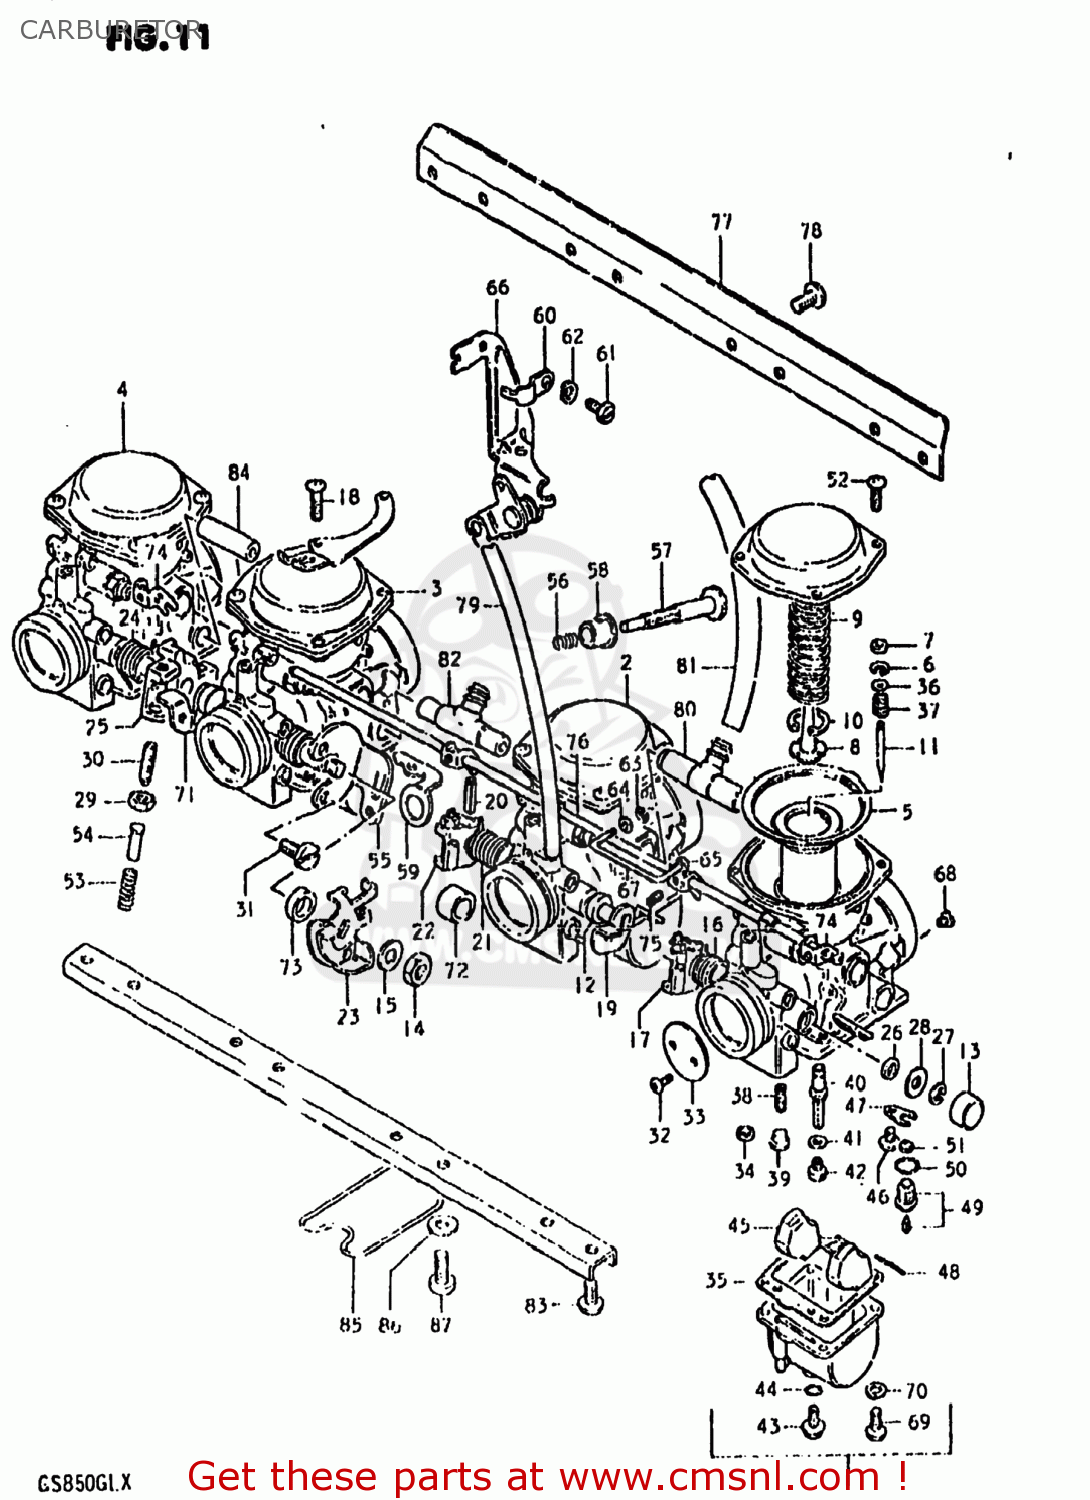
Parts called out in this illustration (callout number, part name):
1	CARBURETOR ASSEMBLY
2	CARBURETOR ASSEMBLY
3	CARBURETOR ASSEMBLY
4	CARBURETOR ASSEMBLY
5	DIAPHRAGM
6	CLIP,NEEDLE
7	RING
8	HOLDER,GUIDE
9	SPRING
10	E RING
11	NEEDLE JET
12	GASKET,THROTTLE SHAFT (NAS)
13	CAP
14	NUT
15	WASHER
16	SPRING,THROTTLE SHAFT
17	SHAFT,THROTTLE
18	SCREW
19	SHAFT ASSEMBLY
20	PIN,THROTTLE SHAFT
21	SPRING,THROTTLE SHAFT
22	LEVER,THROTTLE SHAFT
23	LEVER ASSEMBLY,THROTTLE
24	SPRING,THROTTLE SHAFT
25	SHAFT,THROTTLE
26	SEAL
27	E RING
28	GASKET,THROTTLE SHAFT (NAS)
29	NUT
30	SCREW
31	SCREW
32	SCREW
33	VALVE,THROTTLE
34	GASKET (NAS)
35	GASKET,FLOAT CHAMBER (NAS)
36	WASHER
37	SPRING
38	JET,PILOT
39	PLUG,NEEDLE JET
40	JET,NEEDLE
41	WASHER,NEEDLE NOZZLE
42	JET,MAIN(115)
43	PLUG,DRAIN
44	GASKET (NAS)
45	FLOAT
46	SCREW
47	PLATE
48	PIN,FLOAT
49	VALVE ASSEMBLY,NEEDLE
50	O RING
51	FILTER
52	SCREW
53	SPRING,THROTTLE SCREW
54	PIN,THROTTLE LEVER
55	BRACKET,THROTTLE ADJUST
56	SPRING
57	SCREW
58	BUSH
59	BRACKET,THROTTLE ADJUST
60	BRACKET,STARTER
61	BOLT
62	LOCK WASHER
63	CAP,LEVER
64	SEAT,SPRING
65	LEVER ASSY
66	BRACKET
67	ROD,STARTER LEVER
68	JET,AIR(190)
69	SCREW
70	LOCK WASHER
71	SHAFT ASSEMBLY
72	RING
73	RING
74	LEVER
75	SCREW
76	SHAFT,STARTER
77	BRACKET
78	SCREW
79	HOSE
80	NIPPLE
81	HOSE
82	NIPPLE
83	SCREW 6X12
84	NIPPLE
85	CLAMP
86	WASHER
87	SCREW
